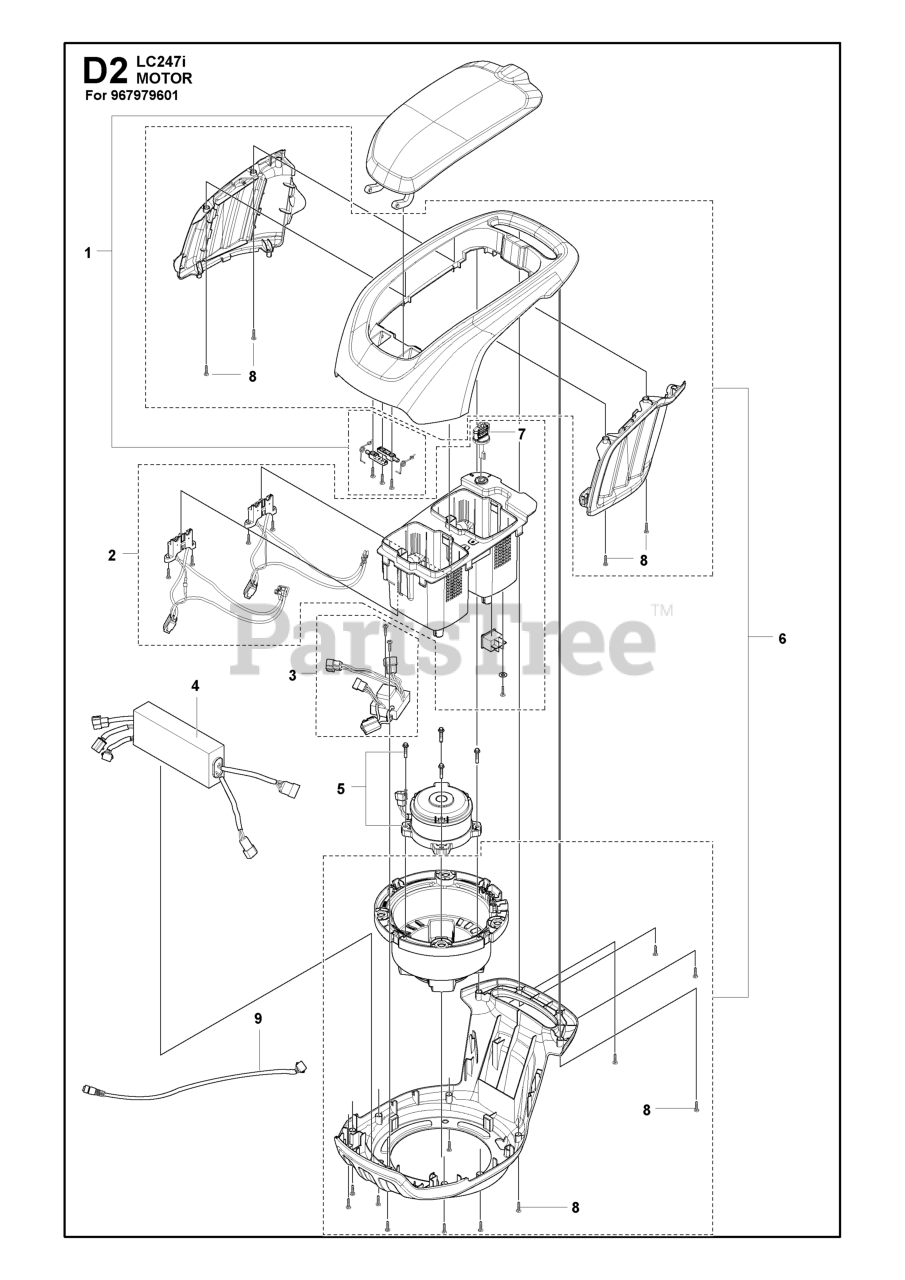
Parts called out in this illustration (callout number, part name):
1	LID ASSY SPARE PART ASSY LC247
2	BATTERY BOX SPARE PART ASSY LC
3	CONTACT PLATE SPARE PART ASSY
6	ENGINE HOOD ASSY POWER UNIT LC
7	KEY
8	SCREW SELF TAPPING DAYE# A2680
